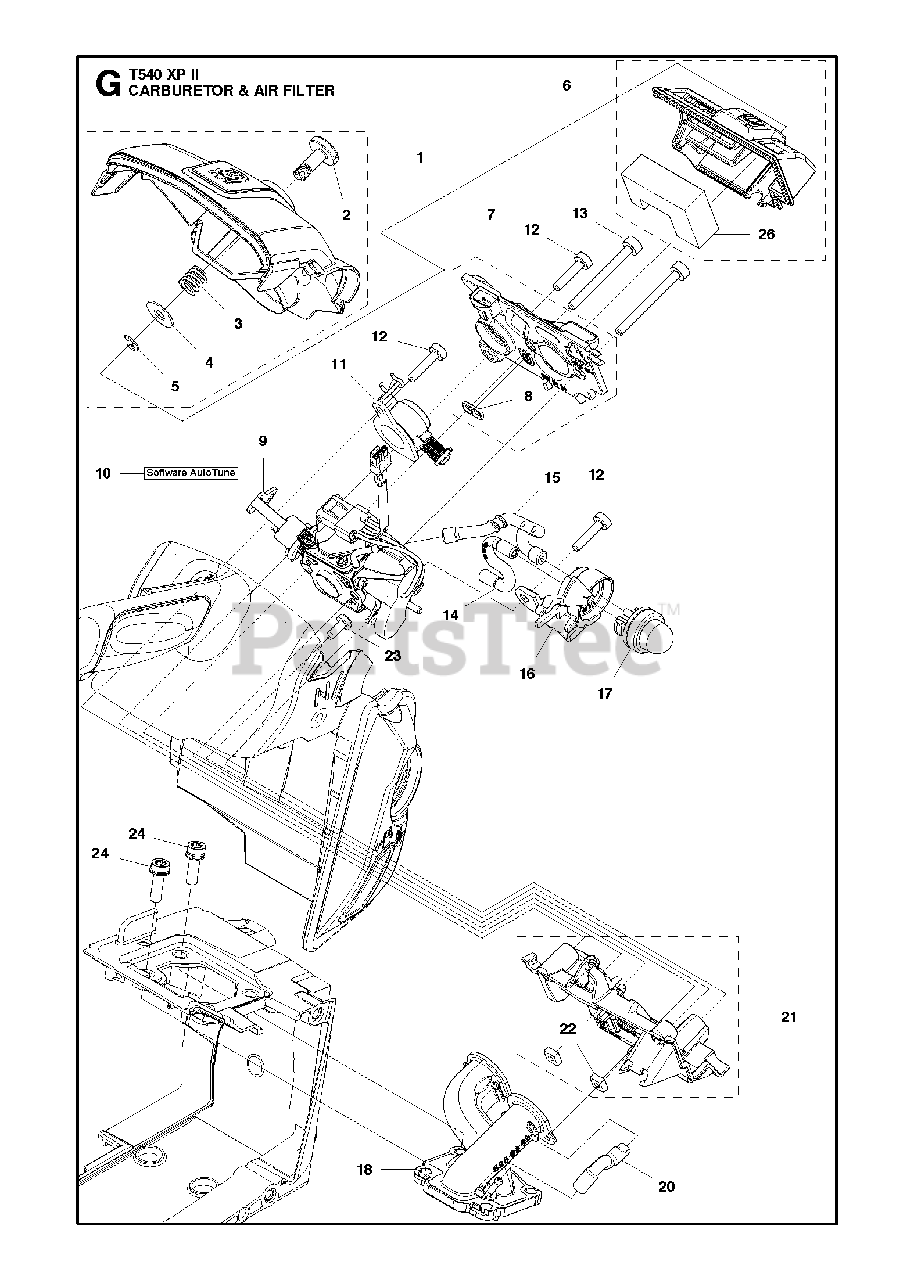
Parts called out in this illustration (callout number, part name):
1	FILTER COVER ASSY
2	KNOB
3	SPRING
4	WASHER
5	E-RING 4
6	AIR FILTER ASSY
6	AIR FILTER
6	AIR FILTER ASSY LN NO
7	FILTER HOLDER ASSY
8	SEALING
9	CARBURETTOR ASSY
10	Husqvarna TBD
11	THROTTLE ASSY
12	SCREW ITXSCT
13	SCREW ITXSCM
15	SUCTION HOSE
16	CHOKE CONTROL ASSY
17	AIR PURGE BUBBLE
18	INLET PIPE ASSY
20	HOSE
21	CARBURETTOR BRACKET
22	NUT SQUARE
23	SCREW CITXPANT
24	SCREW ITXSCM
26	FOAMING FILTER
